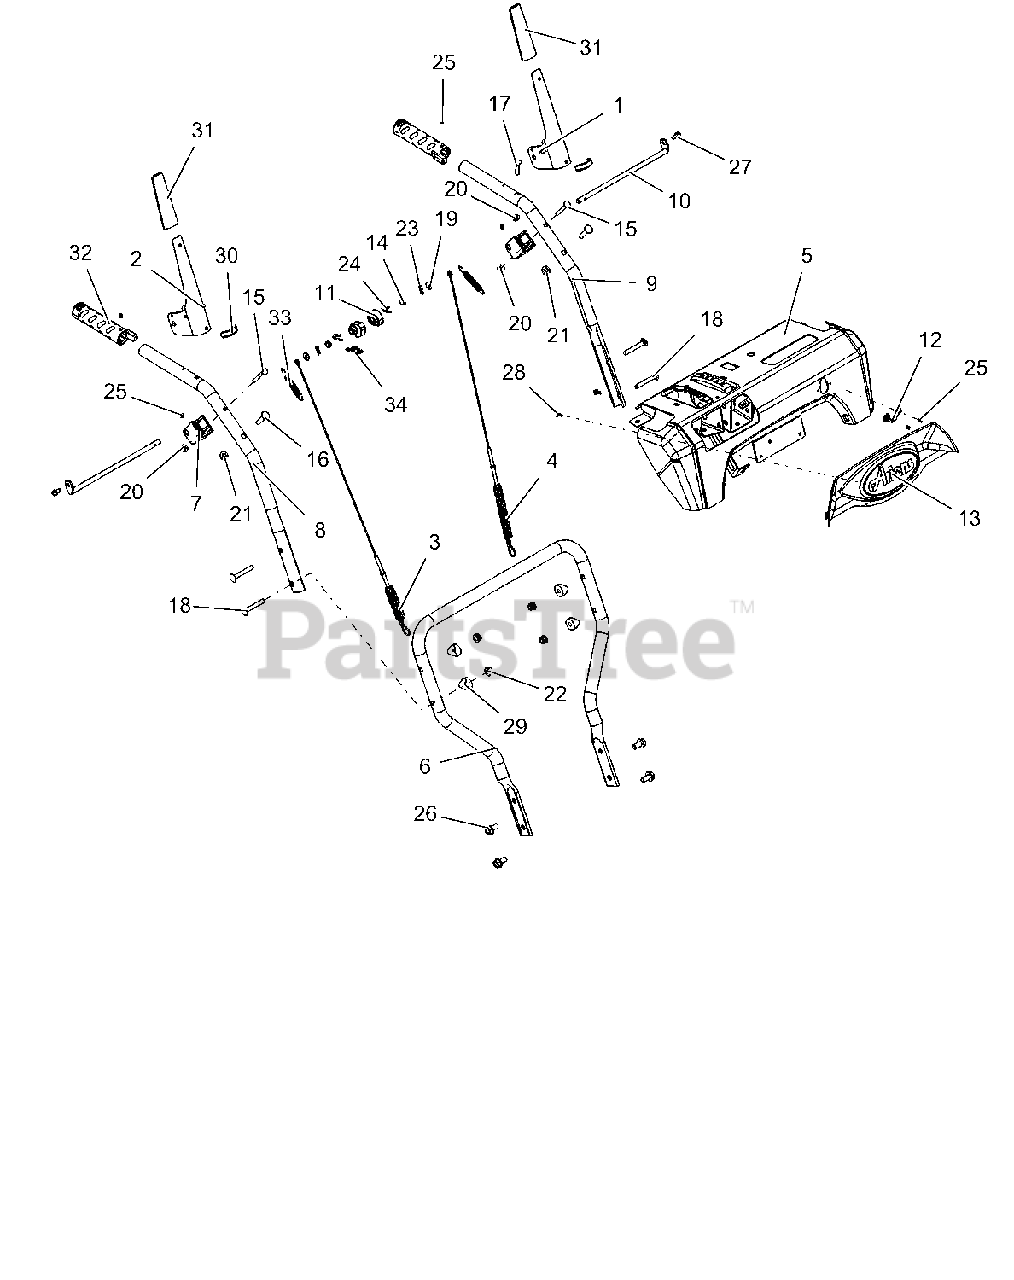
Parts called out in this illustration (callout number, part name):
1	LEVER, CLUTCH-LH
2	LEVER, CLUTCH-RH
3	CABLE, AUGER (DELUXE & PRO)
4	CABLE, UPPER TRACTION
5	CONTROL PANEL W/DECAL FRIC-TRK
6	HANDLEBAR, LOWER - DELUXE
7	BLOCK, CLUTCH PADDLE
8	HANDLEBAR, UPPER - RH
9	HANDLEBAR, UPPER - LH
10	ROD, PADDLE MOUNT - PRO
11	CAM, INTERLOCK
12	GROMMET, CABLE, QUICK TURN 2
13	BEZEL, DASH-ARIENS LG DASH
14	BUSHING, POLYLINER-.38 SNAPIN
15	BLT-RDHDXLSQNK .25-20X2.0 G5YZ
16	@BLT-RDHDSQNK .31-18X1.50 G5YZ
17	BLT-RDHDXLSQNK.25-20X1.25 G5ZC
18	@BLT-RDHDSQNK .31-18X2.25 G5YZ
19	@WSHR-FL-STL.281X.62X.065 YWZC
20	@NUT-LK-CTR-FLG .25-20 YWZC
21	@NUT-LK-TOP-FLG .31-18 YWZC
22	@NUT-LK-NYL-FLG .31-18 YWZC
23	PIN-HAIR INT .06X.18X.77
24	PIN, SPRING CLIP
25	RVT-POP #43 .125X.313 STL ZINC
26	BLT-SERHFWH .38-16X.75 YWZC
27	SCR-TAP .25-20X.50 HWH TR YWZ
28	SCR-TAP #10X.50 BOSS INDHXHD
29	SPACER, HANDLEBAR
30	EDGING, CLUTCH PADDLE - 2.00"
31	SLEEVE, CLUTCH PADDLE-GRAY
32	GRIP,HEATED HANDLE-GRAY
33	SPRING, EXTENSION
34	SPRING-EXT .047X.438X1.45
